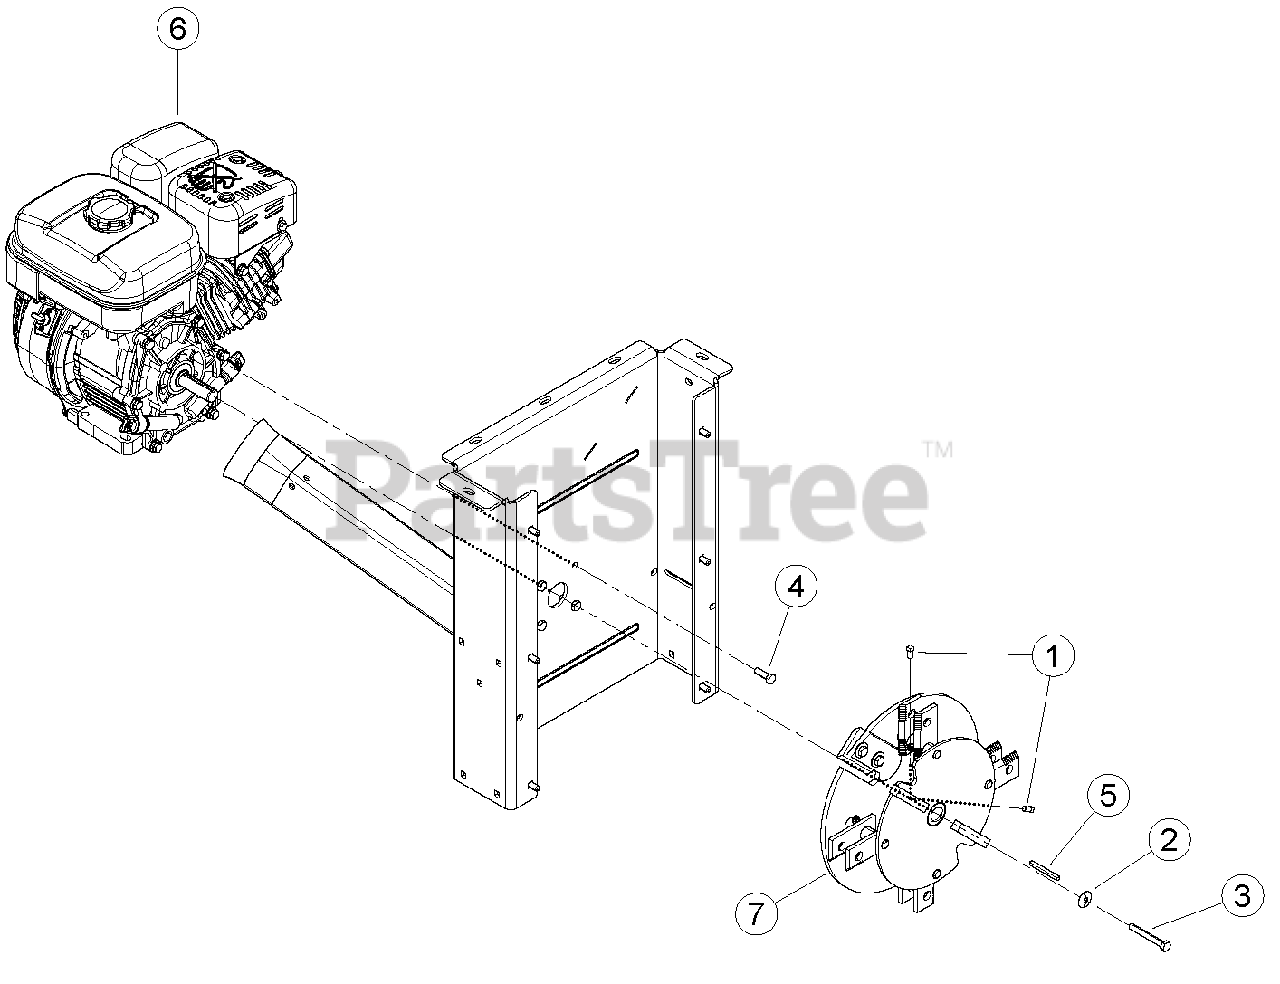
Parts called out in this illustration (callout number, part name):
1	SCREW, 1/4 X 1/2 SQ HD CP SET
2	WASHER, 5/16 GR8 USS FLAT
3	BOLT, 5/16 X 2-1/2 HEX NF GR5 ZP
4	BOLT, 5/16-24 X 1 HEX GR5 ZP
5	KEY, 3/16 X 2 SQ
6	ENGINE, SUBARU 170CC SP170
7	ASSEMBLY, SC2170 ROTOR KNIVES
